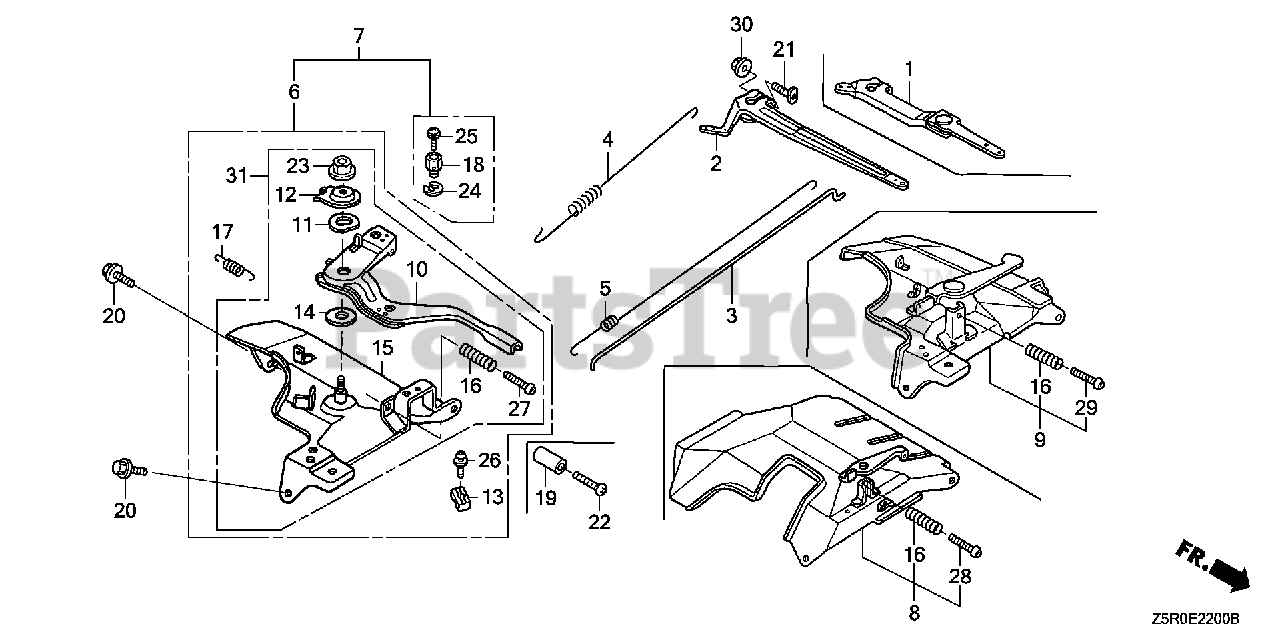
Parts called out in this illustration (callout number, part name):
1	ARM, GOVERNOR
3	ROD, GOVERNOR
4	SPRING, GOVERNOR (L=132.0MM)
5	SPRING, THROTTLE RETURN
6	CONTROL ASSY. (REMOTE)
10	LEVER, CONTROL
11	SPRING, LEVER
12	WASHER, CONTROL LEVER
13	HOLDER, CABLE
14	SPACER, CONTROL LEVER
15	BASE, CONTROL
16	SPRING, CONTROL ADJUSTING
17	SPRING, CABLE RETURN
20	BOLT, FLANGE (6X12) (CT200)
21	BOLT, GOVERNOR ARM
23	NUT, SELF-LOCK (6MM)
26	SCREW, PAN (5X16)
27	SCREW, PAN (5X32)
30	NUT, FLANGE (6MM)
